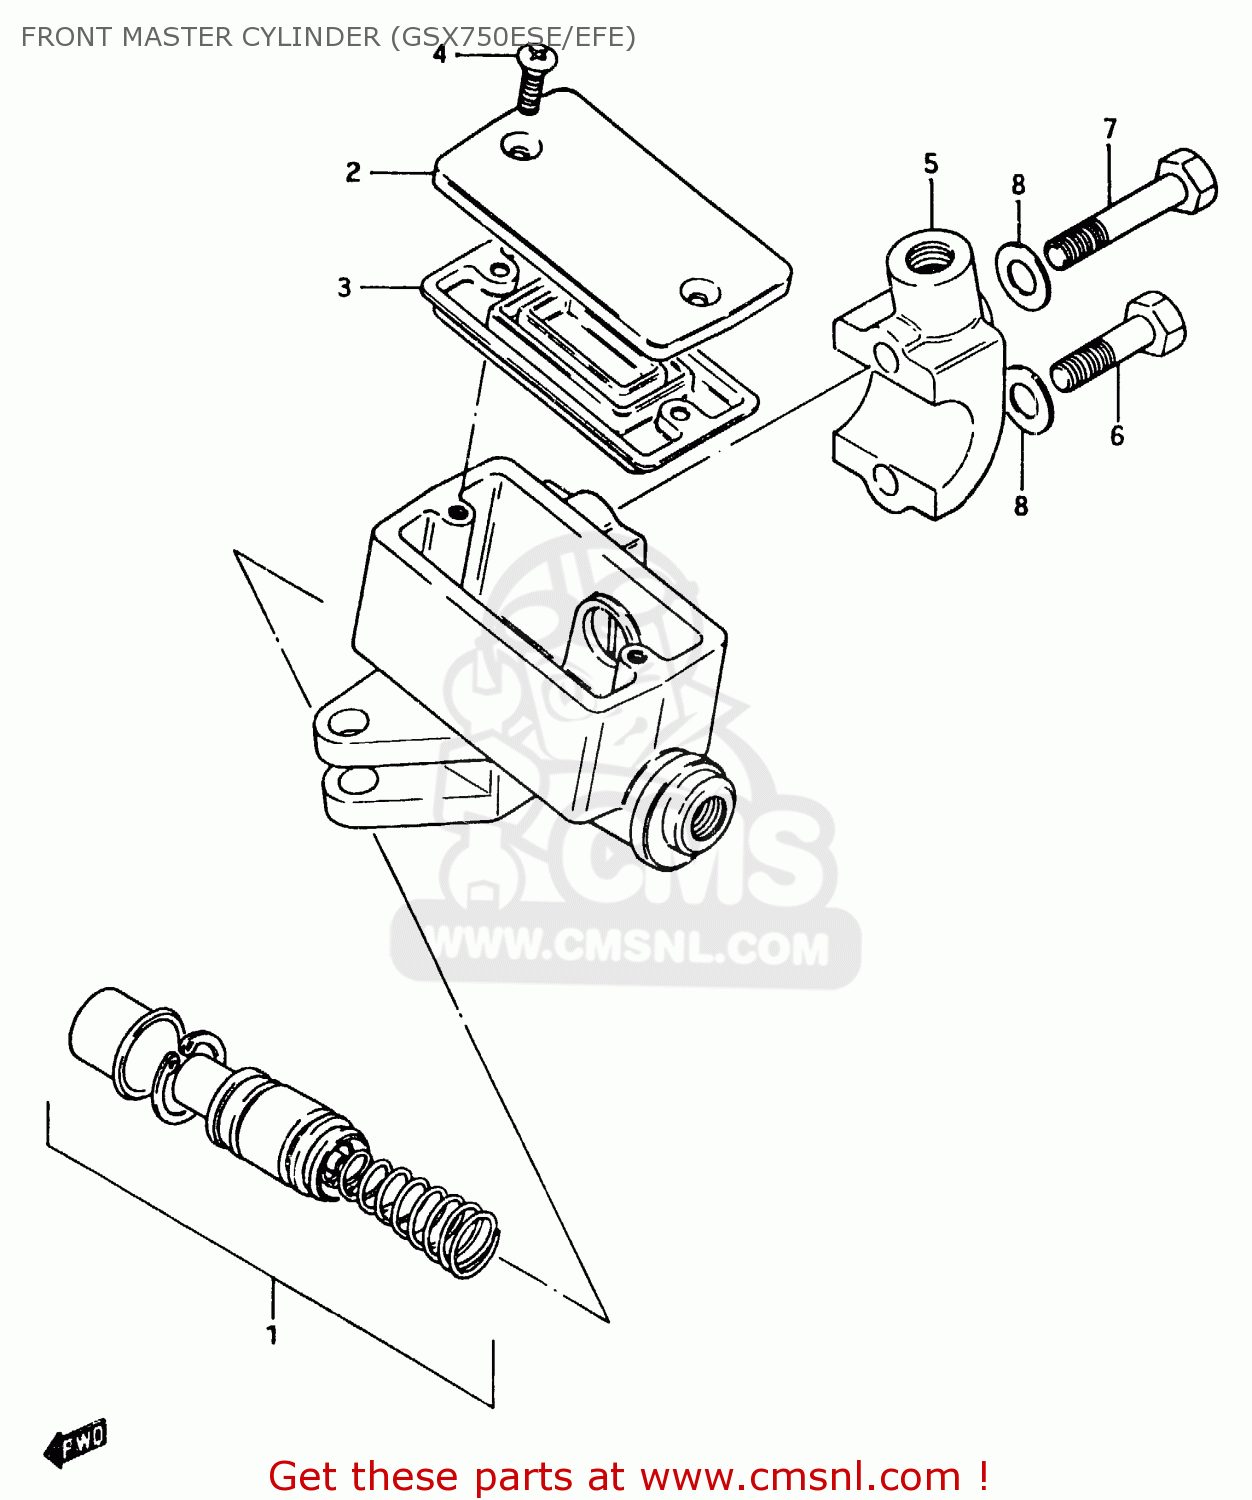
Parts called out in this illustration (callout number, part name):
1	PISTON & CUP SET
2	CAP
3	4
4	SCREW
5	HOLDER
6	BOLT
7	BOLT
8	WASHER
